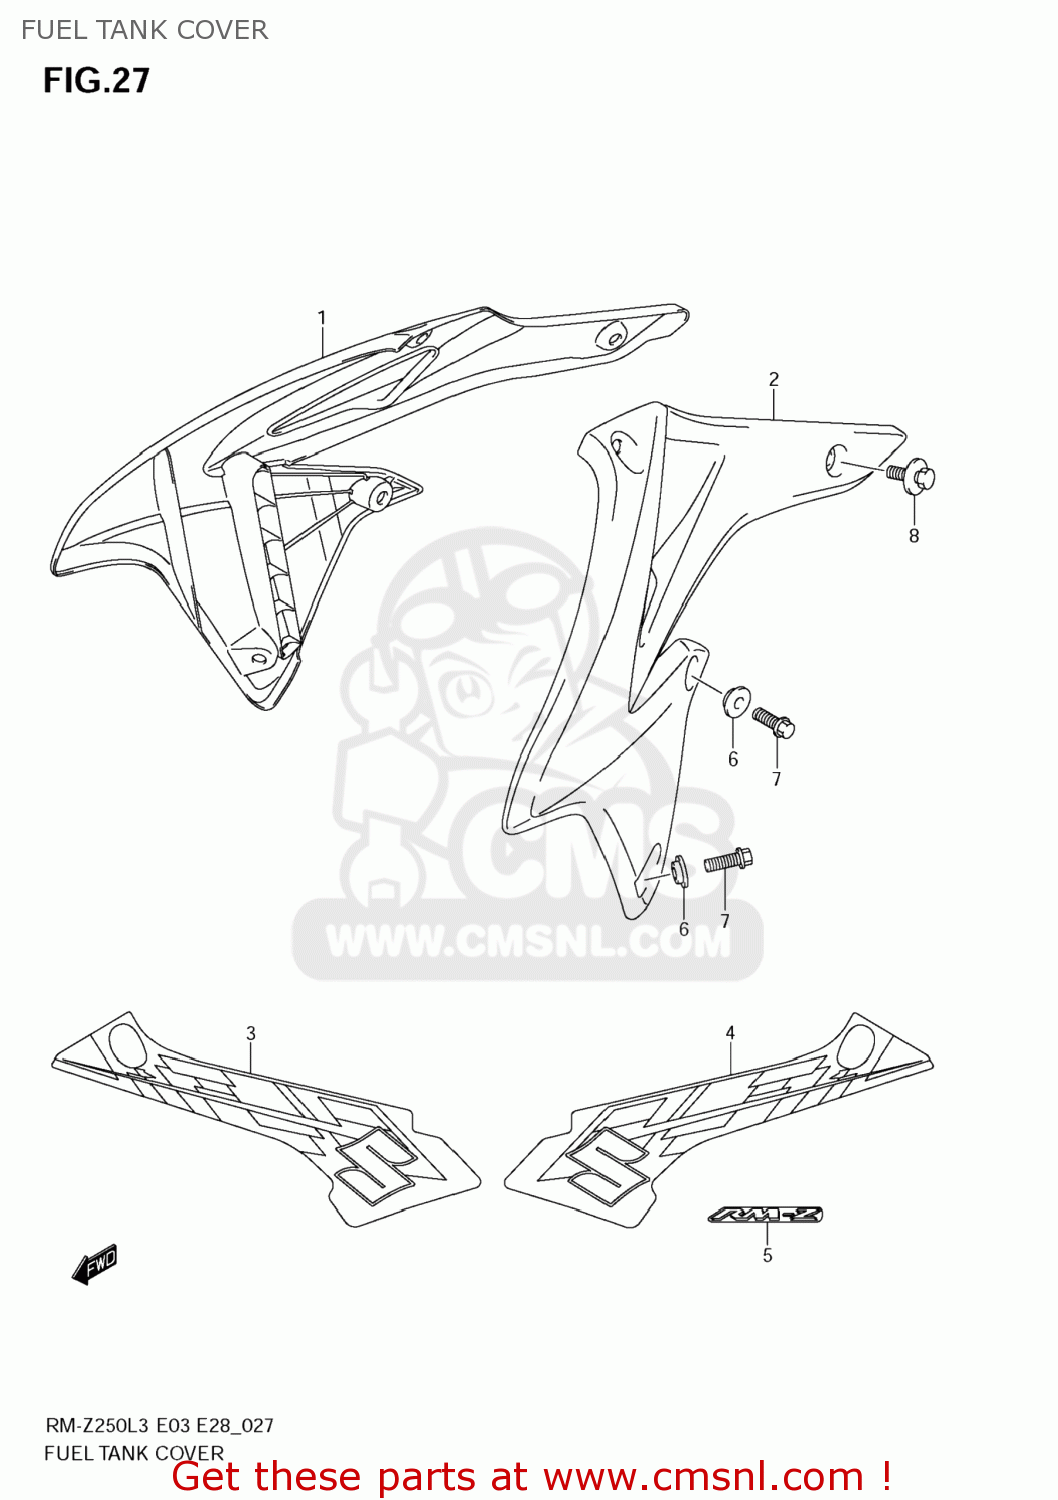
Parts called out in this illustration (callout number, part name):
1	COVER,FUEL TANK,R
2	COVER,FUEL TANK,L
3	TAPE,FUEL TANK COVER,R
4	TAPE,FUEL TANK COVER,L
5	EMBLEM,RADIATOR COVER
6	WASHER,FR FENDER
7	BOLT
8	BOLT(6X12)
